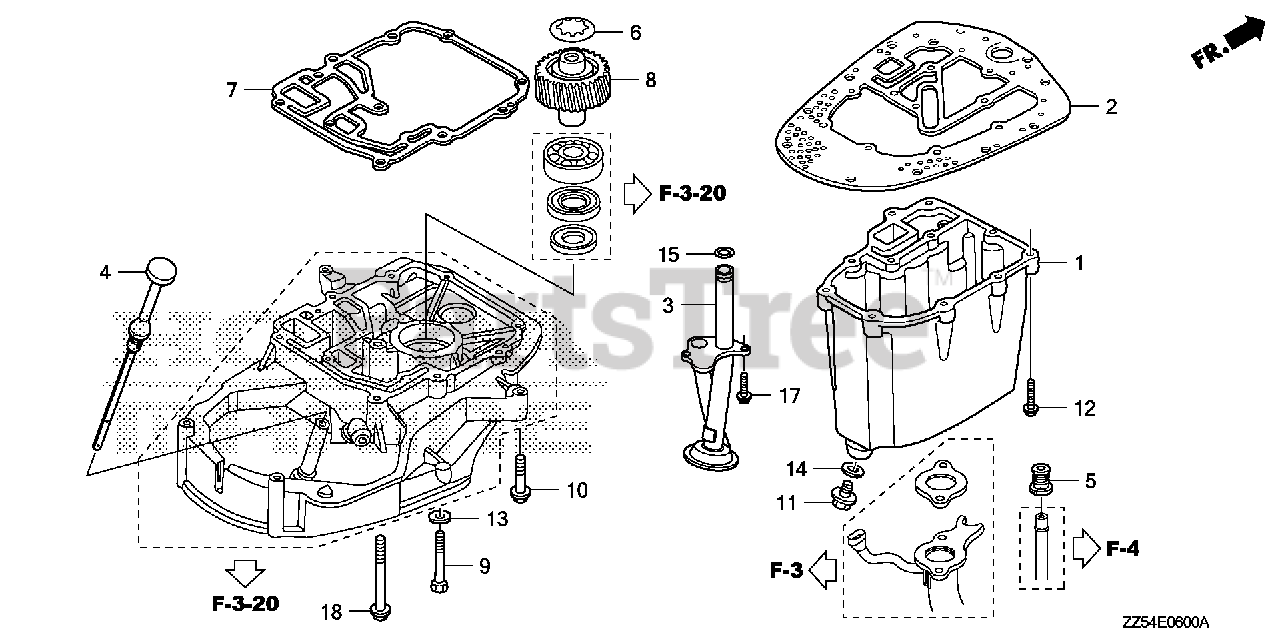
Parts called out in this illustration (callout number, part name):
1	PAN, OIL *TGRAY* (GRAY)
2	GASKET, OIL PAN
3	STRAINER, OIL
4	DIPSTICK, OIL
5	GROMMET, WATER TUBE
6	SPRING, THRUST
7	GASKET, PRIMARY GEAR CASE
8	GEAR, PRIMARY DRIVEN (33T)
9	BOLT, HEX. (8X55)
10	BOLT, FLANGE (8X35)
11	BOLT, DRAIN PLUG
12	BOLT, FLANGE (6X25) (SUS-D)
13	WASHER, PLAIN (8MM) Use up to Frame SN 4800712.
14	WASHER, DRAIN PLUG (12MM)
15	O-RING (13.8X2.5)
17	BOLT, FLANGE (6X16) Use from Engine SN 2056820.
18	BOLT, FLANGE (8X75)
